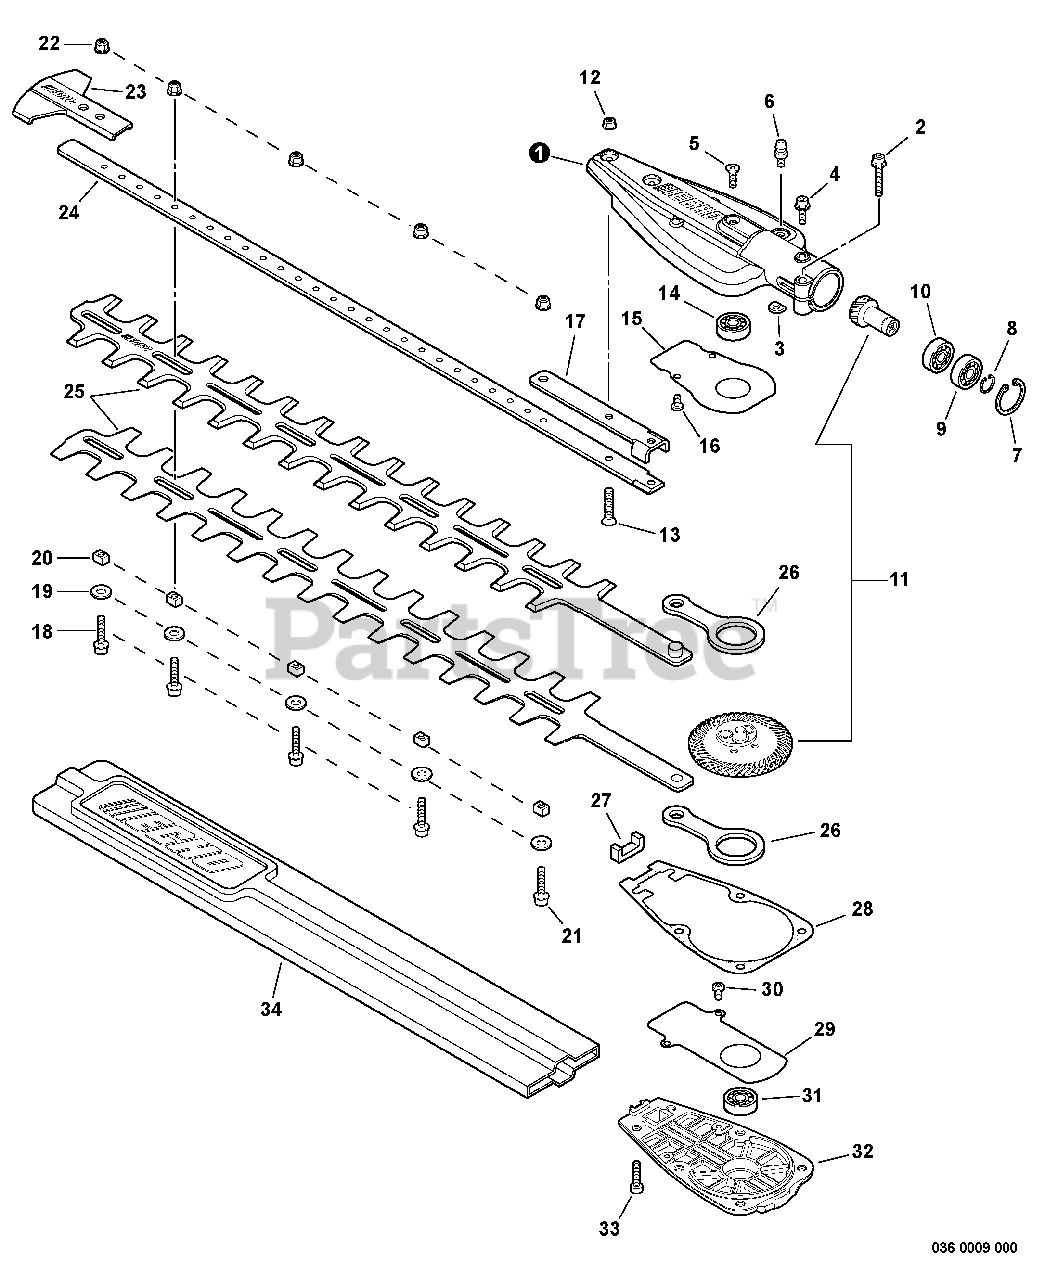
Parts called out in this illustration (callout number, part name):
1	CASE, GEAR
2	SCREW - 5X25
4	SCREW - 5X12
5	SCREW - 5X8
6	FITTING, GREASE
7	RING, RETAINING - 24
8	RING, RETAINING - 12
9	BEARING, BALL - 6901
10	BEARING, BALL - 6901Z
11	GEAR SET
12	NUT - 5 -- FLANGE
13	SCREW - 5X18
14	BEARING, BALL - 608ZZ
15	PLATE, WEAR
16	SCREW - 4X5
17	SUPPORT, BLADE
18	SCREW - 5X20
19	WASHER - 6
20	GUIDE, BLADE
21	SCREW - 5X22
22	LOCKNUT - 5
23	GUARD, TIP
24	SUPPORT, BLADE
25	BLADE, TRIMMER
26	ROD, CONNECTING
28	GASKET, GEAR CASE
29	PLATE, WEAR
30	SCREW - 4X5
31	BEARING, BALL - 628ZZ
32	LID, GEAR CASE
33	SCREW - 5X12
34	COVER, BLADE
